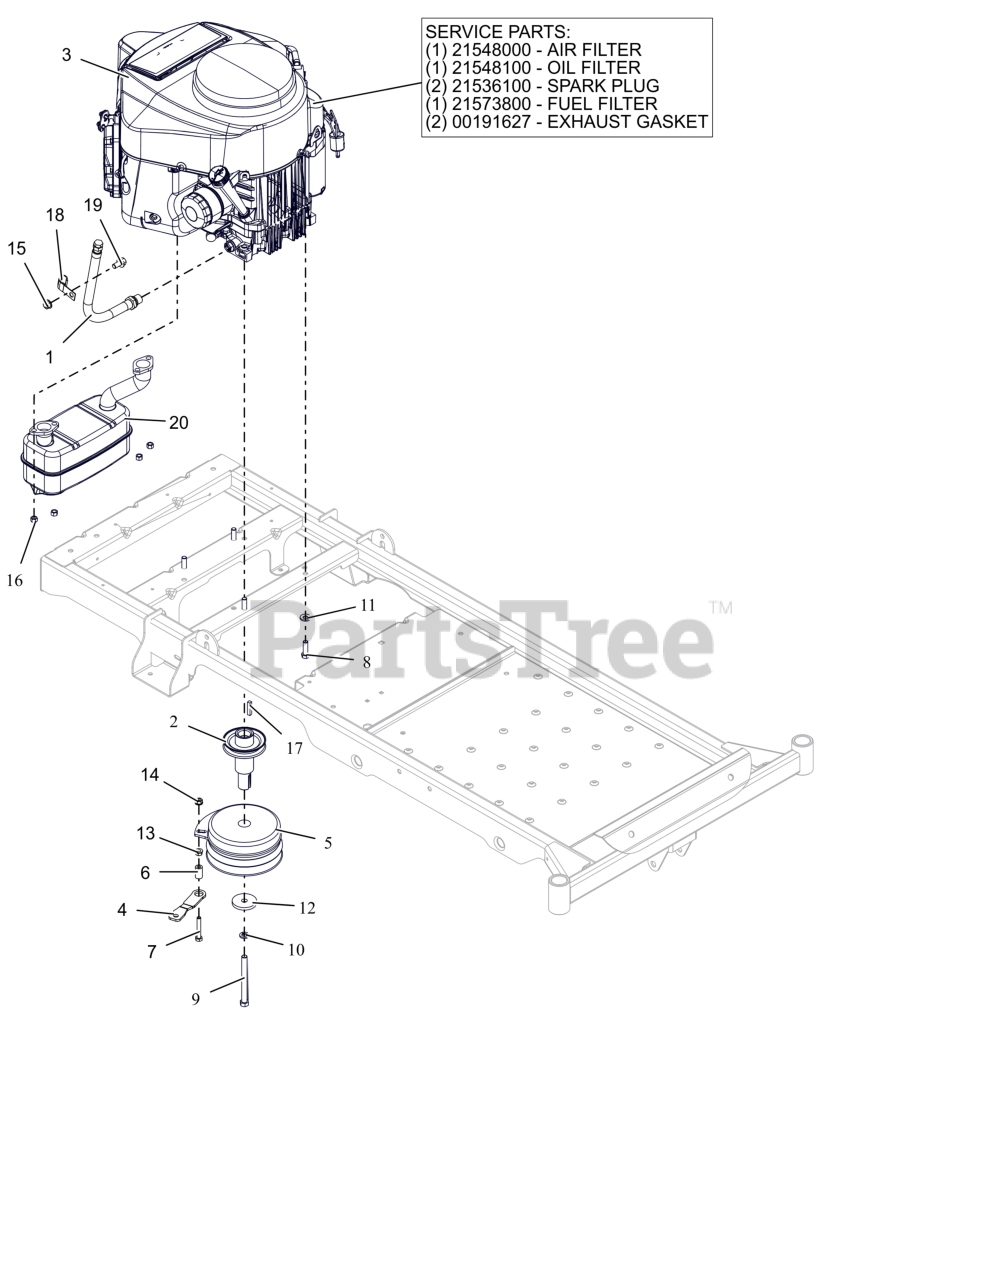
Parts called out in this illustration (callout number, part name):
1	HOSE, OIL DRAIN
2	WLDMT, CRANKSHAFT EXTENSION
3	ENGINE, KAWASAKI FR651V
3	AIR FILTER, KAWASAKI FR
3	OIL FILTER, KAWASAKI FR
3	PLUG, SPARK
3	FUEL FILTER
3	GASKET, MUFFLER S/O
4	BRKT, CLUTCH
5	CLUTCH, 105 FT*LB MONO POLE
6	SPACER, RUBBER 5/16 IDX1.0 LG
7	BLT, HEX .31-18X2.00 G5 ZCC
8	BLT, HEX .38-16X1.25 G5 ZCC NT
9	BLT, HEX .44-20X4.50 G8 ZCC NT
10	WSHR, LK-REG .438X.109 ZCC
11	WASHER, 3/8" SPRING DISC
12	WSHR, FLT .469X2.00X.250 ZCC
13	NUT,SPNLK-FLG .31-18 G5 ZCC
14	NUT,LK-CTR-FLG .31-18 GF ZCC
15	NUT-LK-CTR-FLG .375-16 GF ZCC
16	NUT-LK-TOP-FLG M8 ZCC
17	KEY-SQ .25 X 1.25 X .25 SAE
19	BLT, SERHFWH 0.375-16X0.75 GR5 ZCC
20	MUFFLER, KAWASAKI TWIN
